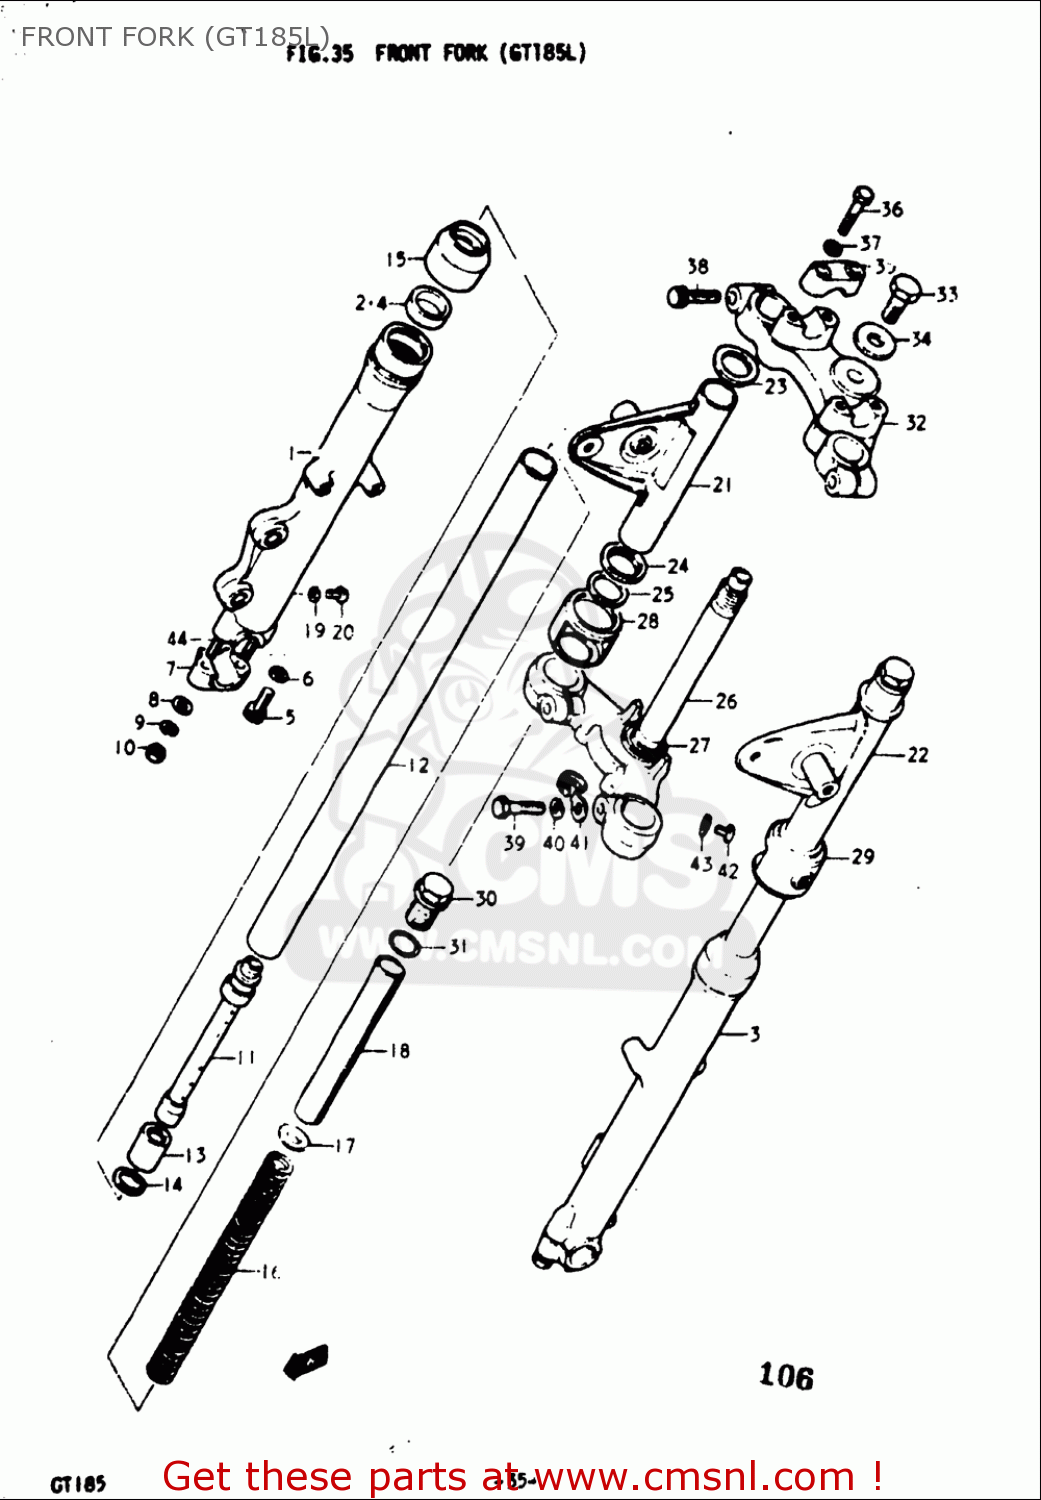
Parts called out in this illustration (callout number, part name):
2	SEAL,OIL
4	SEAL,OIL
6	GASKET (NAS)
8	WASHER
9	WASHER,LOCK
10	NUT
14	RING,SNAP
15	SEAL,DUST
17	GUIDE,SPRING COVER
19	GASKET,DRAIN,PLUG (NAS)
20	SCREW
21	BRACKET,HEADLAMP HOUSING
22	BRACKET,HEADLAMP,LEFT
23	SEAT,HEADLAMP BRACKET
24	SEAT,HEADLAMP BRACKET
25	CUSHION,HEAD LAMP BRACKET
27	RACE,STEERING OUTER LWR
30	BOLT,FR FORK
31	O RING
32	HEAD,STEERING STEM
33	BOLT,FR FORK(10X33)
34	WASHER
35	HOLDER,HANDLE(BLACK)
36	BOLT
37	WASHER,LOCK
38	BOLT
40	WASHER,LOCK
42	SCREW
43	WASHER,LOCK
44	BOLT,STUD
